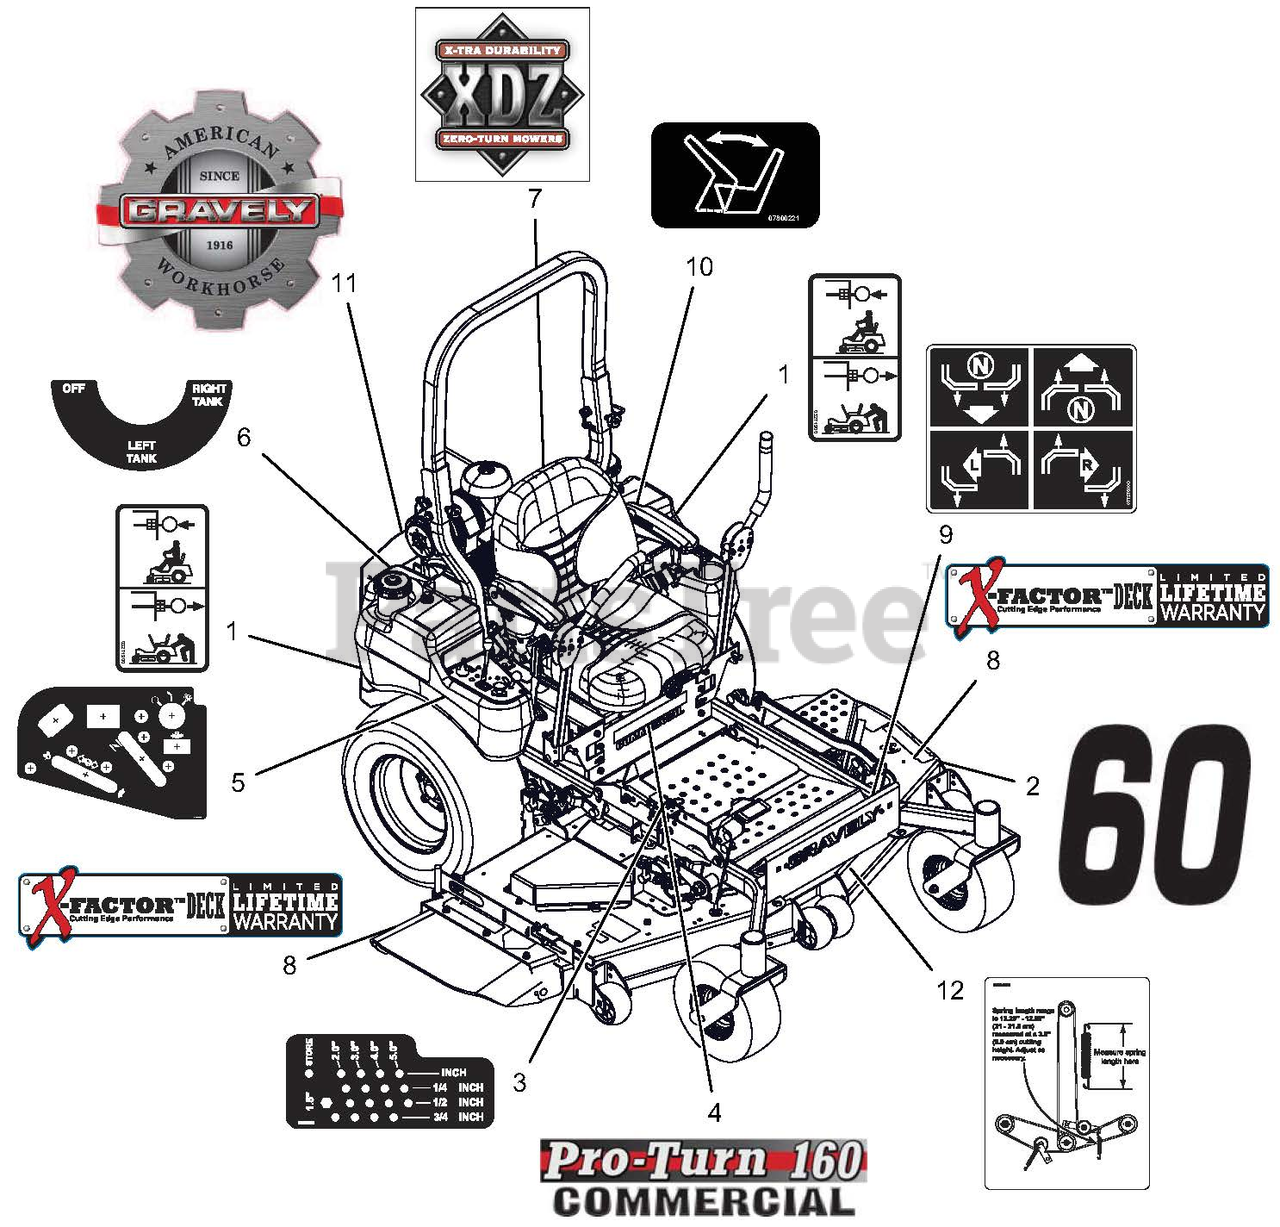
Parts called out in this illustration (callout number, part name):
1	DECAL, TRANSMISSION DISCONNECT
2	DECAL, 60"
3	DECAL, HEIGHT OF CUT
4	DECAL, PRO-TURN 160
5	DECAL, CONTROL PANEL
6	DECAL, FUEL VALVE
7	DECAL, XDZ
8	DECAL, X-FACTOR DECK
9	DECAL, INSTRUCTIONAL - STEERING
10	DECAL, SEAT RELEASE
11	DECAL, GRAVELY HERITAGE-LARGE
12	DECAL, BELT DIAGRAM 60"
